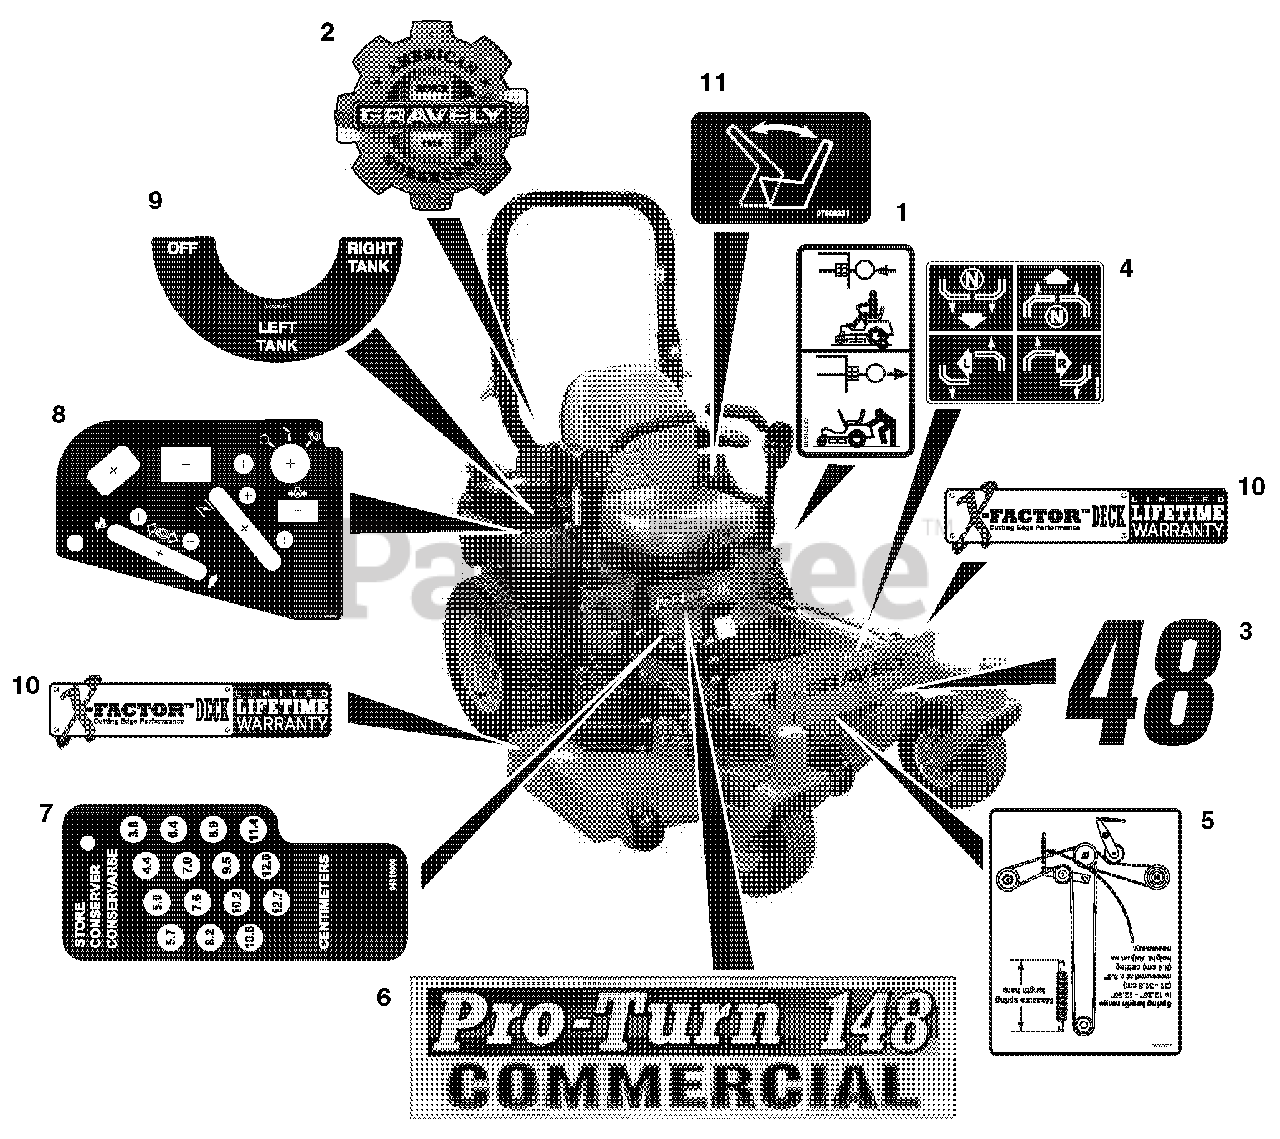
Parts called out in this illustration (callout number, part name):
1	Decal, Transmission Disconnect
2	Decal, Gravely Heritage, Large
3	Decal, 48
4	Decal, Instructional-Steering
5	Decal, Belt Routing
6	Decal, Pro-Turn 148
7	Decal, PT100 CE Height of Cut
8	Decal, Control Panel
9	Decal, Fuel Valve
10	Decal, X-Factor Deck
11	Decal, Seat Release
